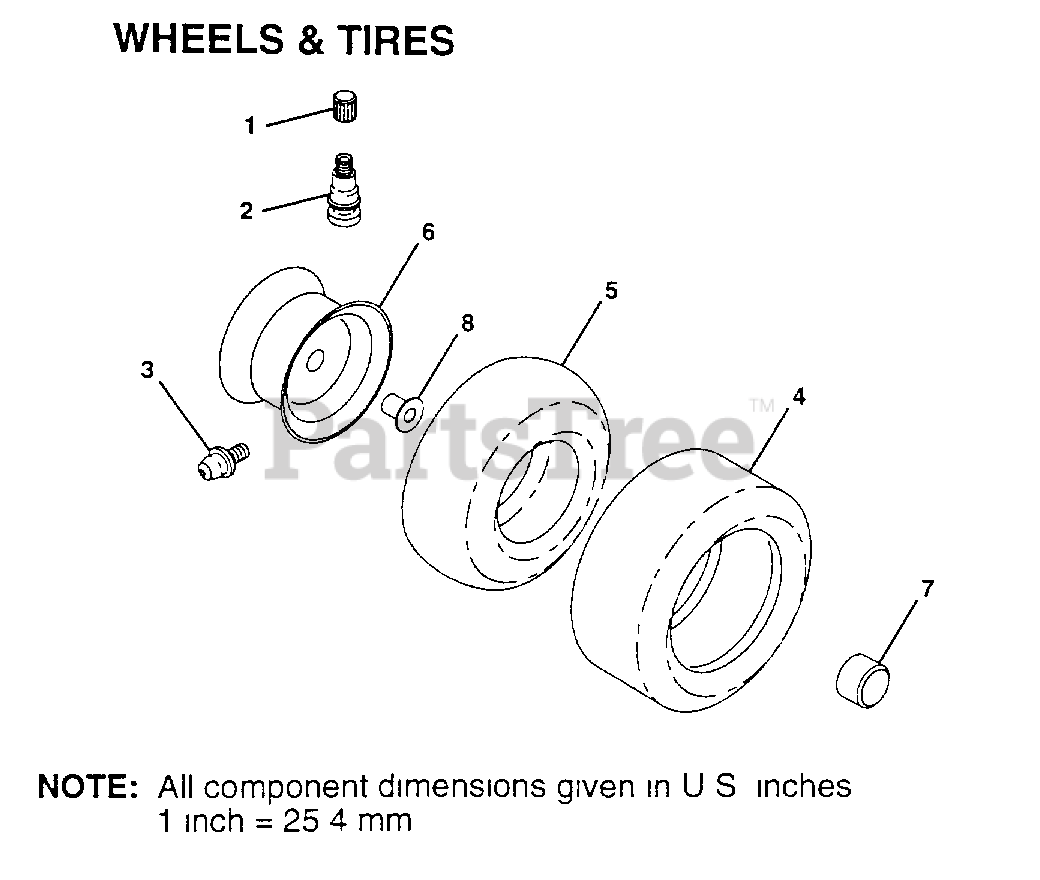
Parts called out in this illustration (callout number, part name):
1	VALVE CAP
2	VALVE STEM LT
3	FITTING LT
4	TIRE.R.23X9.5-12
5	TUBE.5.3/4.5/6
5	TUBE.23X8/10-12
6	"RIM ASM FRT 8"""
6	"RIM.ASM.REAR.12"""
7	HUB CAP
8	"FLANGE, BEARING"
